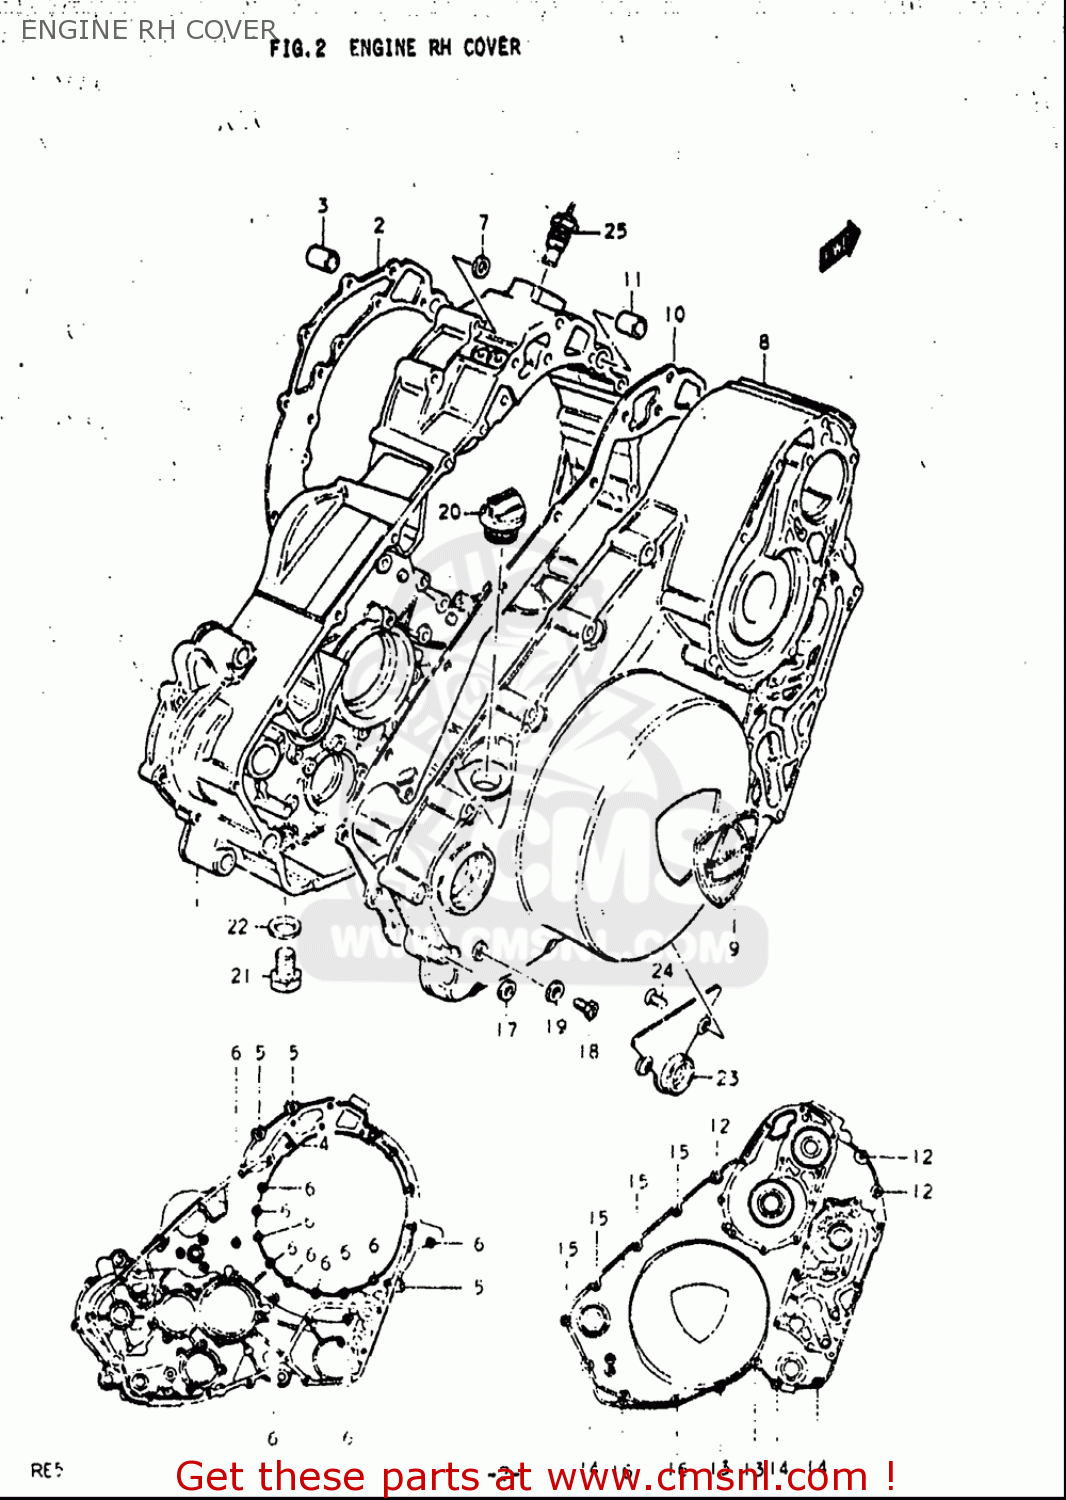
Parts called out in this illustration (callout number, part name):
3	PIN
6	BOLT
7	WASHER
11	PIN
14	BOLT
16	BOLT
17	WASHER
18	SCREW(6X10)
19	GASKET(6.2X11X1) (NAS)
20	PLUG
21	PLUG
22	GASKET(14X19.2X2) (NAS)
25	GAUGE ASSY,WATER TEMP
